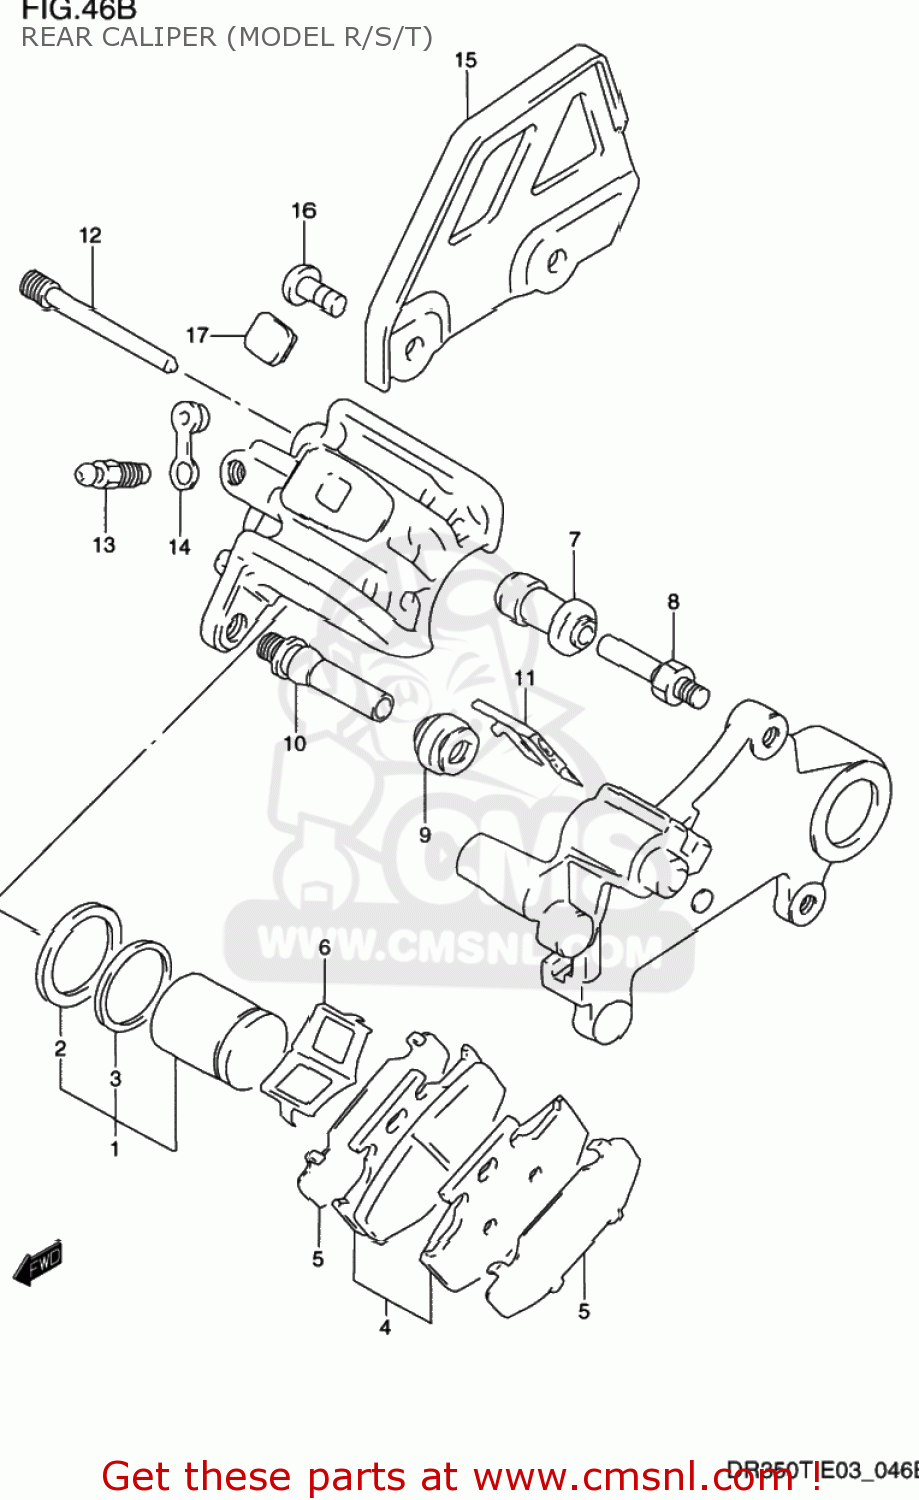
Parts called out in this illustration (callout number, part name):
1	PISTON SET
2	SEAL,PISTON
3	SEAL,DUST
4	PAD SET (NAS)
5	SHIM
6	SPRING,PAD
7	BOOT
8	PIN,BOLT
9	BOOT
10	PIN
11	RETAINER,BRACKET
12	PIN,HANGER
13	BLEEDER
14	CAP,BLEEDER
15	GUARD,RR CALIPER
16	SCREW 6X12
17	COVER,RR CALIPER BODY
